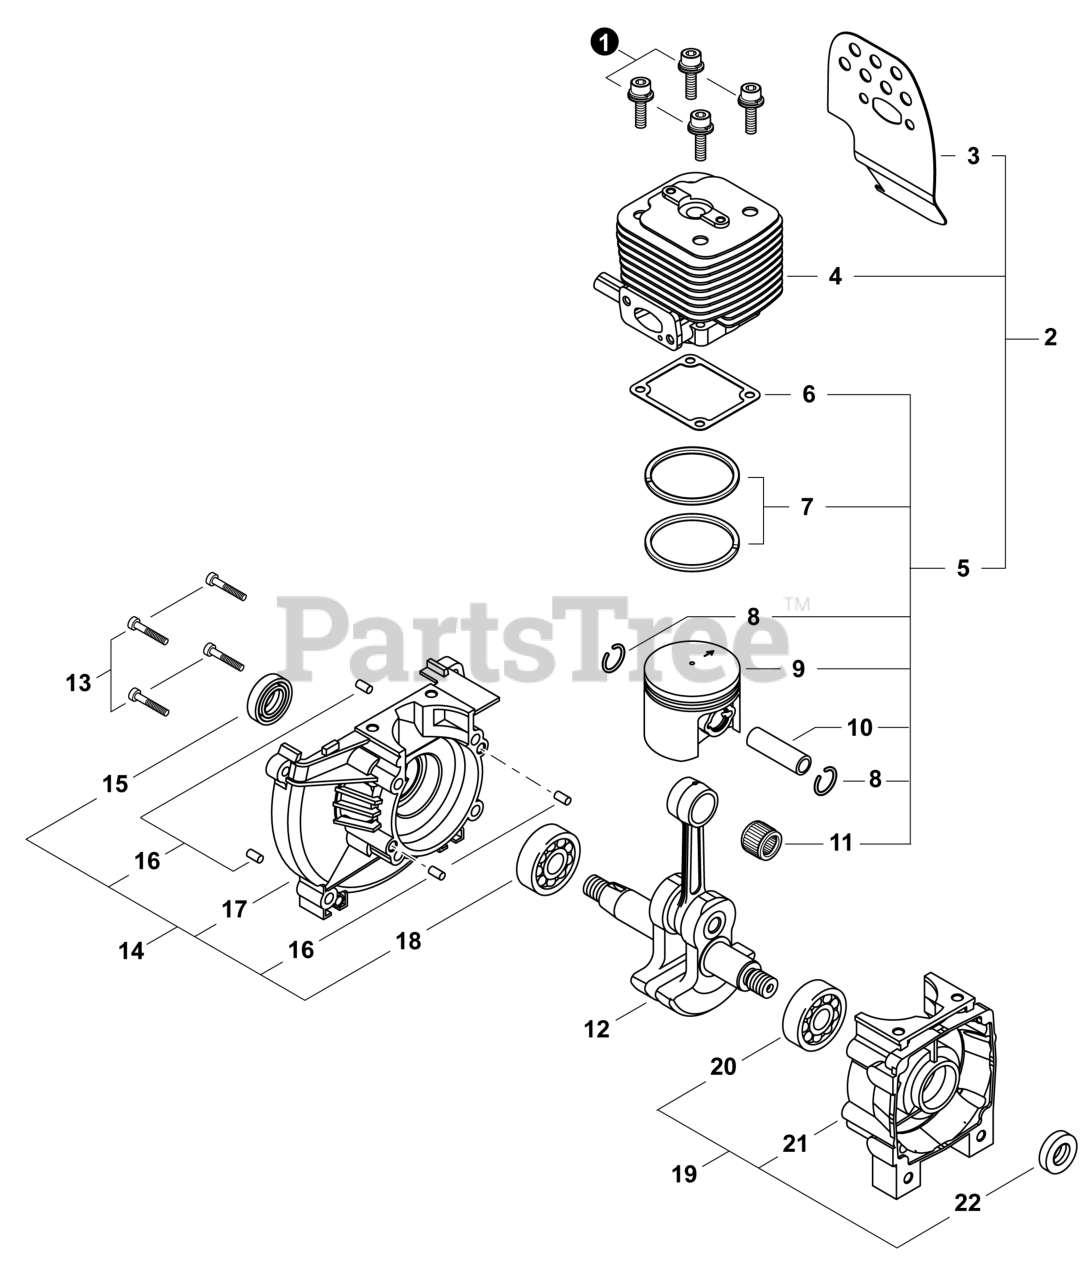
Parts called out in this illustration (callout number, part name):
1	BOLT M5×25
2	REPAIR KIT, ENGINE
3	HEAT SHIELD, EXHAUST
4	CYLINDER
5	PISTON KIT
6	GASKET, CYLINDER
7	RING, PISTON
8	RING, SNAP
10	PIN, PISTON
11	BEARING, NEEDLE
12	CRANKSHAFT
13	BOLT 5×30
14	CRANKCASE ASSY, M
15	SEAL, OIL 16
16	PIN, LOCATING 5×10
17	CRANKCASE M
18	BEARING, BALL 6202 C3
19	CRANKCASE ASSY, S
20	BEARING, BALL 6202 C3
21	CRANKCASE S
22	SEAL, OIL 16
